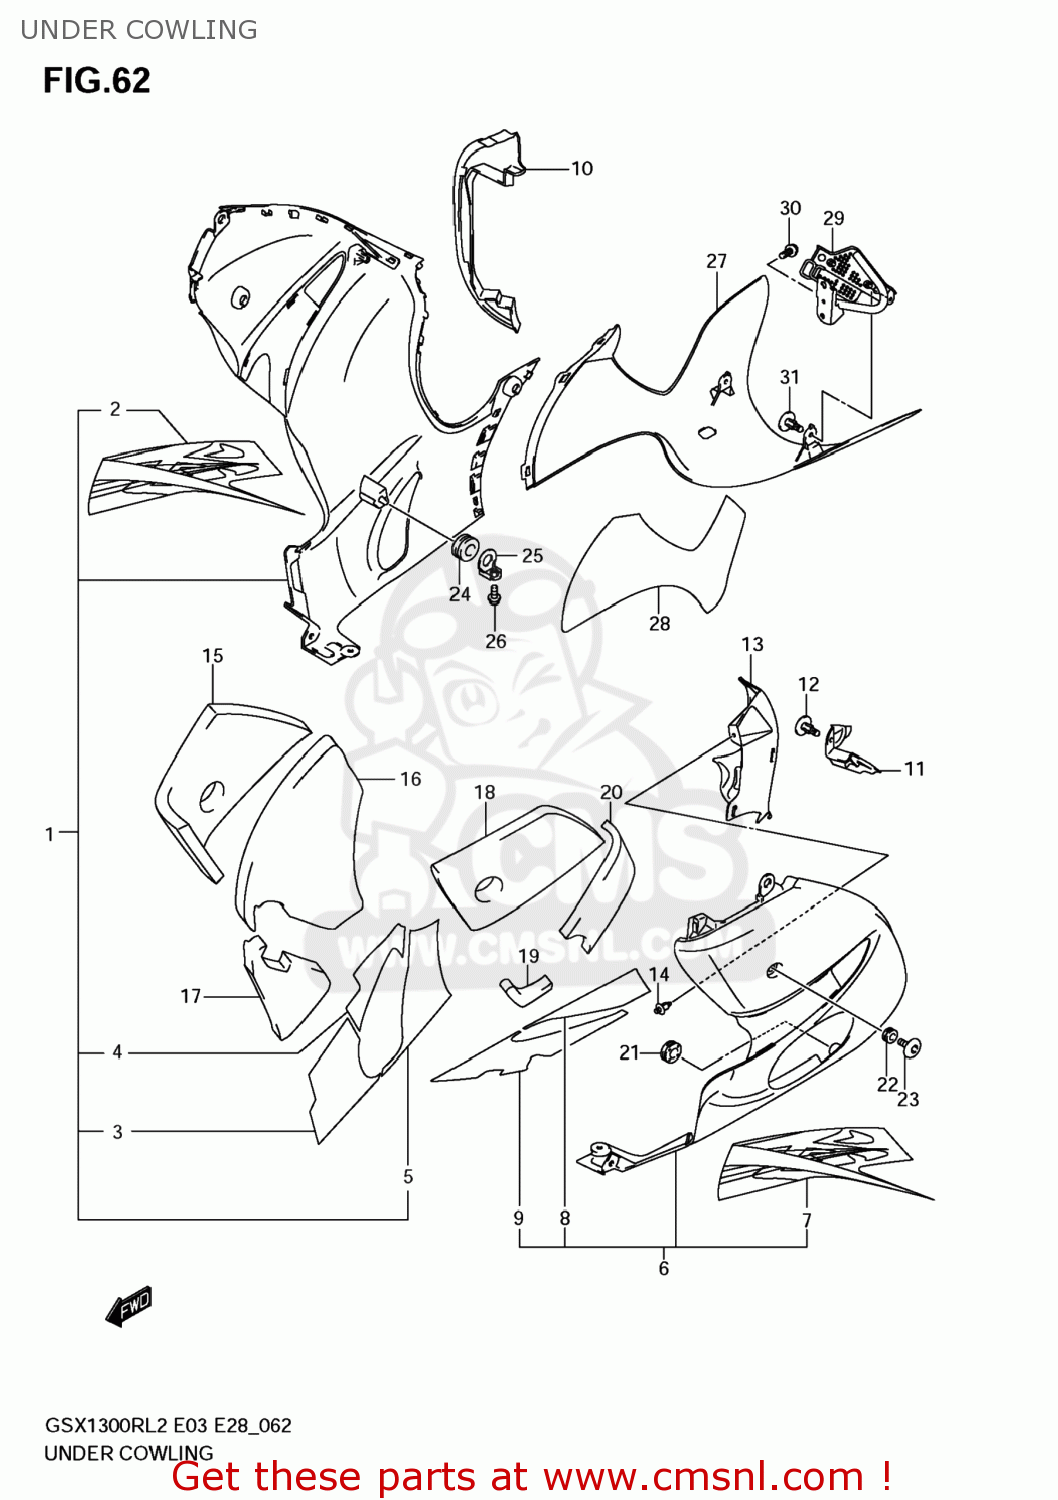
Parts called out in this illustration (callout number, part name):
1	COWLING,UNDER,R(RED)
2	TAPE,UNDER COWL,R
3	SHIELD,UNDER COWL HEAT,R NO.1
4	SHIELD,UNDER COWL HEAT,R NO.3
5	SHIELD,UNDER COWL HEAT,R NO.2
6	COWLING,UNDER,L(RED)
7	TAPE,UNDER COWL,L
8	SHIELD,UNDER COWL HEAT,L NO.1
9	SHIELD,UNDER COWL HEAT,L NO.2
10	PROTECTOR,COWLING UNDER,R
11	PROTECTOR,COWLING UNDER,L
12	CLIP
13	COVER,UNDER COWL,L
14	CLIP(BLACK)
15	CUSHION,UNDER COWLING,R NO.1
16	CUSHION,UNDER COWLING,R NO.2
17	CUSHION,UNDER COWLING,R NO.3
18	CUSHION,UNDER COWLING,L NO.1
19	CUSHION,UNDER COWLING,L NO.2
20	CUSHION,UNDER COWLING,L NO.3
21	CUSHION,UNDER COWLING,L
22	CUSHION
23	SCREW(6X20)
24	CUSHION
25	PLATE,UNDER COWL
26	BOLT
27	COWLING,UNDER RR
28	SHIELD,UNDER COWL HEAT
29	BRACKET,RR UNDER COWLING
30	BOLT
31	CLIP
